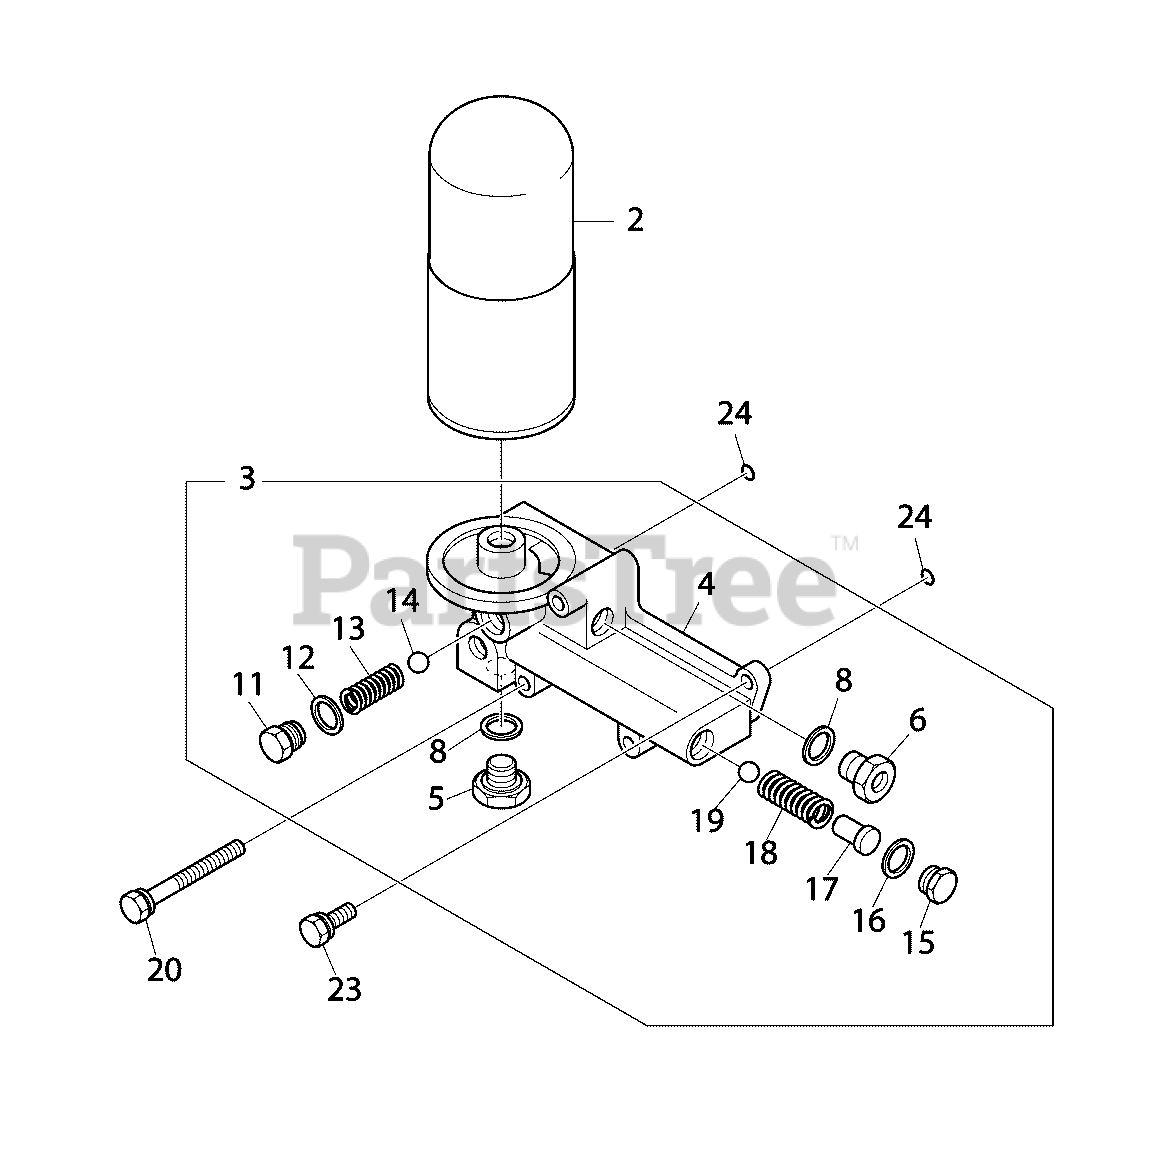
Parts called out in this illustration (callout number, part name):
2	FILTER, OIL, 11.1L PSI
3	* FILTER, OIL HEAD
4	* FILTER, OIL HEAD
5	* PLUG, SCREW
6	* PLUG, SCREW
8	* SEAL, RING
11	* PLUG, SCREW
12	* SEAL, RING
13	* SPRING, O/FILTER
14	* BY-PASS VALVE
15	* PLUG, SCREW
16	* SEAL, RING
17	* PIN, SPRING
18	* SPRING
19	* VALVE, BYPASS
20	* BOLT
23	* BOLT
24	* O-RING
